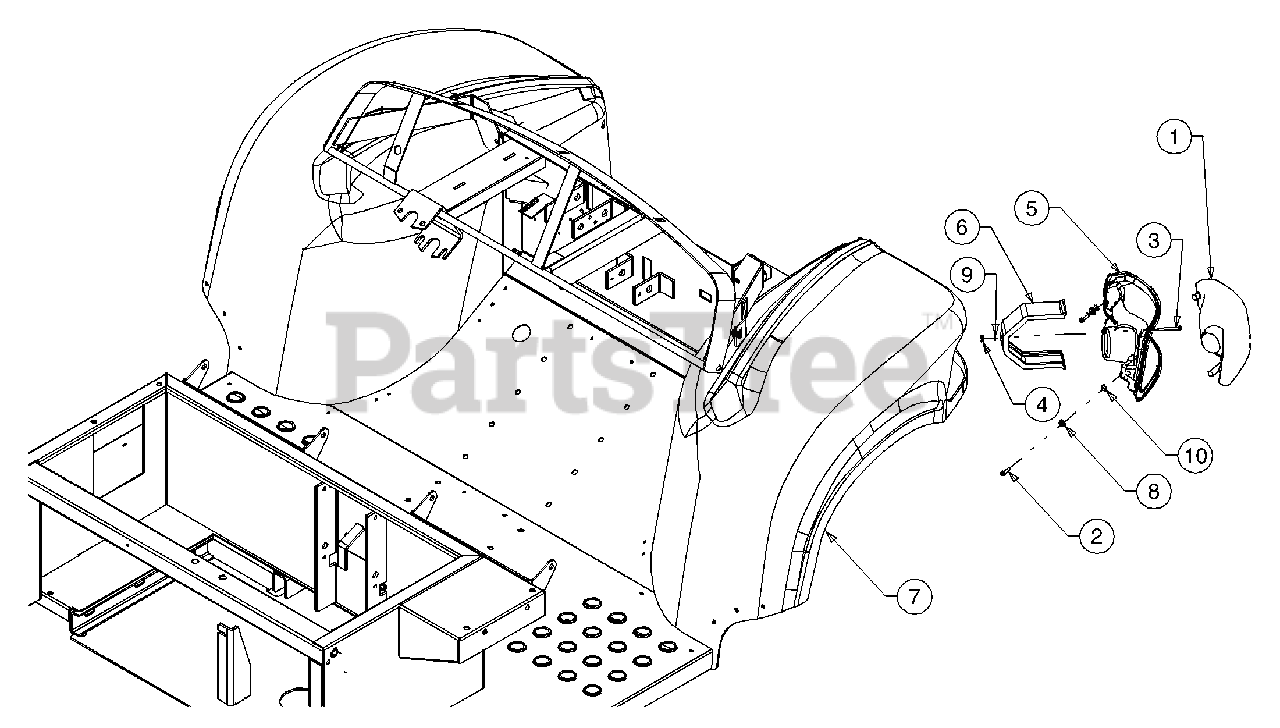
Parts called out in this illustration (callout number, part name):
1	Headlight Assembly, LH
1	Headlight Assembly, RH
2	Hex Screw, Hi-Lo, #10 x .75l
3	Screw, Machine, #8-32 x 1.500
4	Nut, #8-32
5	Panel, Headlight, Bezel, RH
5	Panel, Headlight, Bezel, LH
6	Bracket, Headlight
7	Panel, Right-front Fender
7	Panel, Left-front Fender
8	Washer, Flat, .219 x .500 x .049
9	Washer, Lock, #10, Regular Duty
10	Washer, Flat, .162 x .438 x .041
